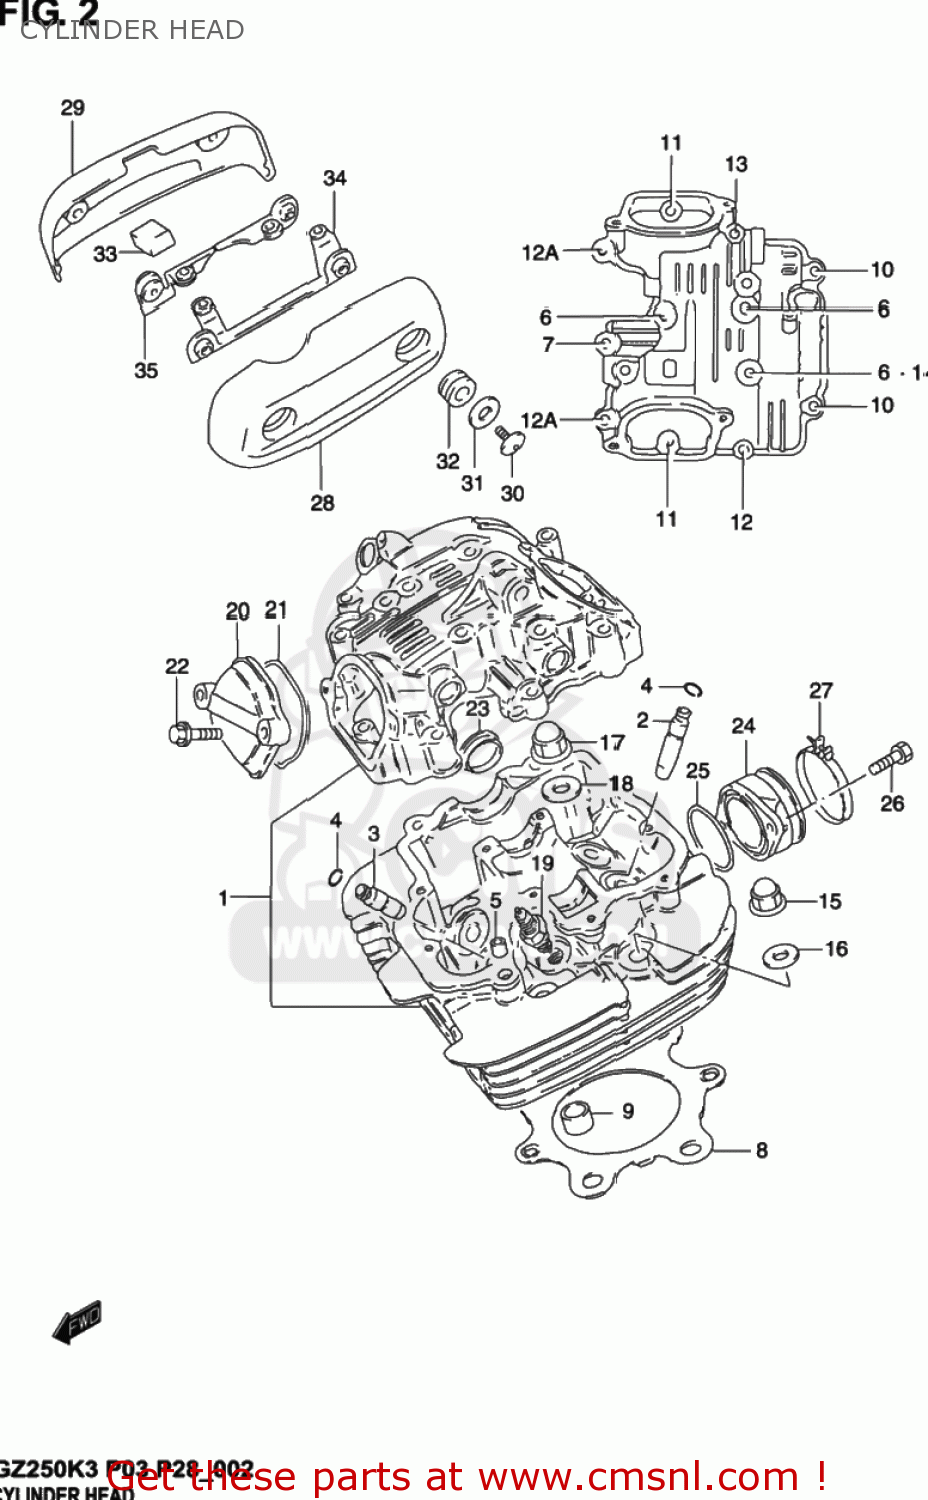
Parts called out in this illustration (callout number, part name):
1	HEAD ASSEMBLY,CYLINDER
2	GUIDE,INTAKE VALVE
3	GUIDE,VALVE
4	RING,SNAP
5	PIN(6.2X8X11)
6	BOLT
7	BOLT
8	GASKET,CYLINDER HEAD (NAS)
9	PIN
10	BOLT(6X120)
11	BOLT
12	BOLT (6X45)
12A	BOLT
13	BOLT
14	GASKET(5.8X13X1.2) (NAS)
15	NUT
16	WASHER(10.5X22X2.3)
17	NUT
18	GASKET(10.5X22X2) (NAS)
19	PLUG,SPARK(DR8EA)
20	CAP,INSPECTION
21	O RING(D:2.4,ID:23)
22	BOLT
23	PLUG(OD:30)
24	PIPE,INTAKE
25	O RING(D:2.4,ID:39.7)
26	SCREW ,6X16
27	CLAMP
28	CAP,CYLINDER HEAD COVER,L
29	CAP,CYLINDER HEAD COVER,R
30	BOLT
31	WASHER(6.5X24X1.6)
32	CUSHION
33	DAMPER,HEAD CAP,R
34	BRACKET,HEAD CAP,L
35	BRACKET,HEAD CAP,R
